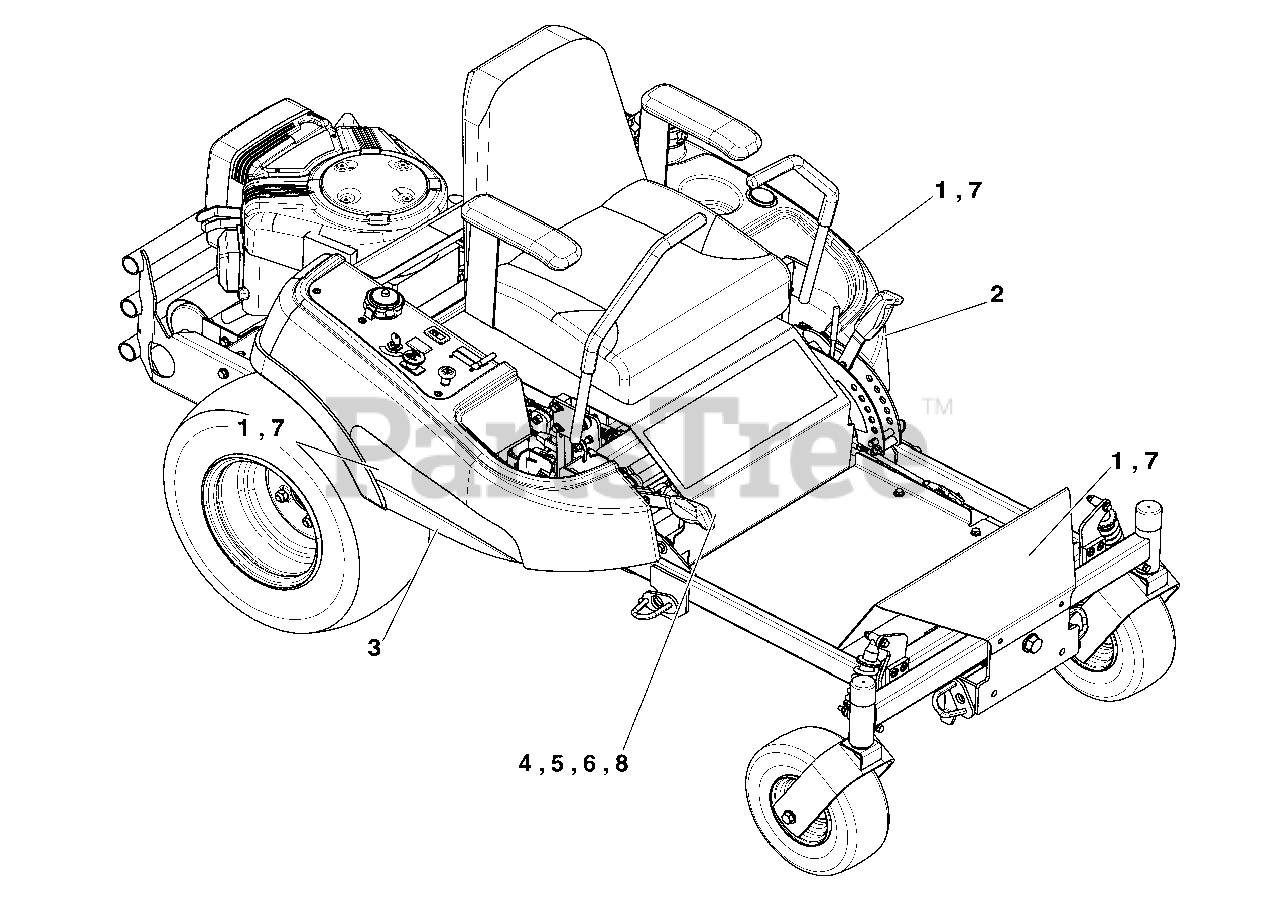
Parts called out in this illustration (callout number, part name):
1	DECAL, SIMPLICITY LOGO, GV3079178
2	DECAL, STRIPE, LH, SIMPLICITY
3	DECAL, STRIPE, RH, SIMPLICITY
4	DECAL, SIMPLICITY, CHAMPION
5	DECAL, 3000Z
6	DECAL, LOGO, CHAMPION
7	DECAL, SMI LOGO, 10.47"
8	DECAL, BRAND NAME, CHAMPION HD
